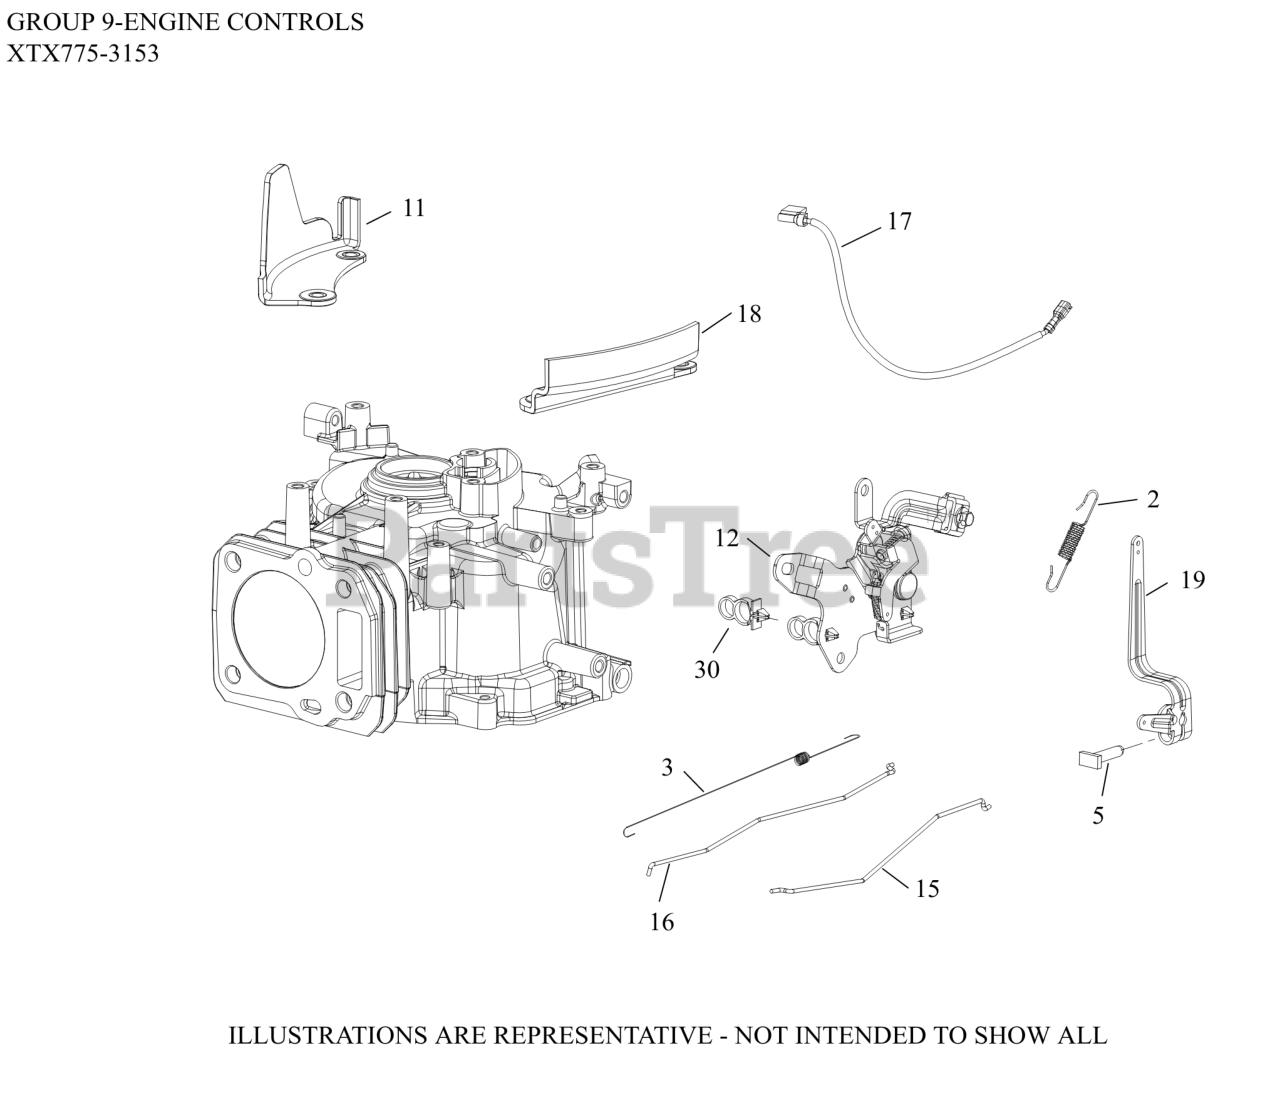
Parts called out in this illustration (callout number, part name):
2	SPRING, GOV (2800-3300 RPM)
3	SPRING, LINKAGE
5	SCREW, RECTANGLE HEAD (M6)
11	GUARD, FINGER
12	CONTROL ASSY, REMOTE VARIABLE SPEED
15	LINKAGE, CHOKE
16	LINKAGE, GOVERNOR
18	GUARD, FINGER
19	LEVER, GOVERNOR
30	CLIP, FUEL LINE
